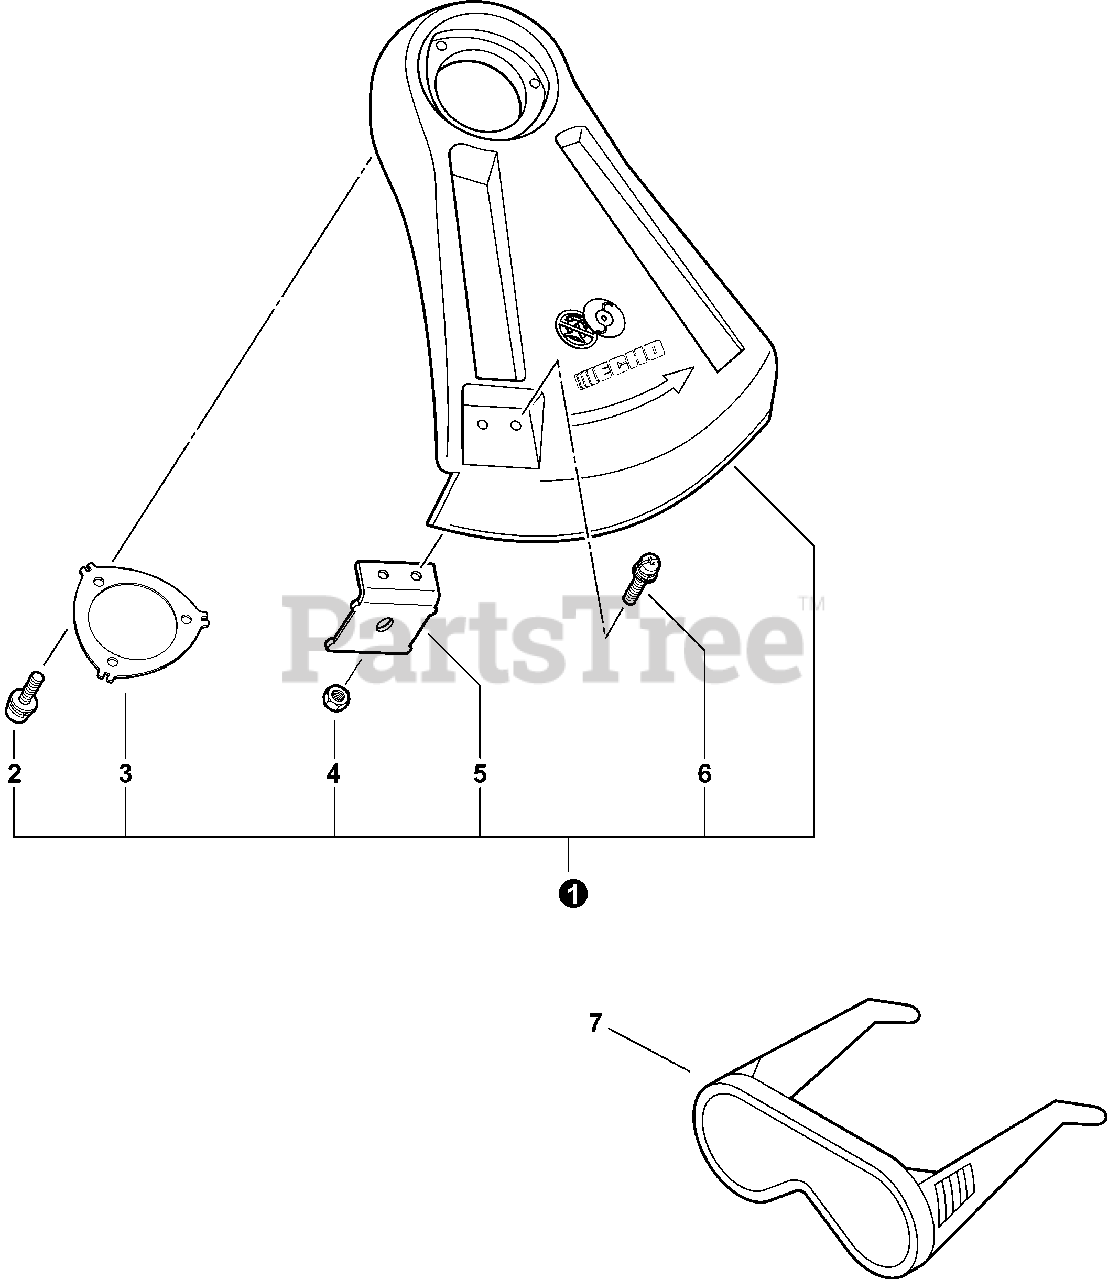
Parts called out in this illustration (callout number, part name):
1	SHIELD ASY
2	SCREW 5×16
3	BRACKET, SHIELD
5	CUTTER
6	SCREW 5×12
7	GOGGLES
